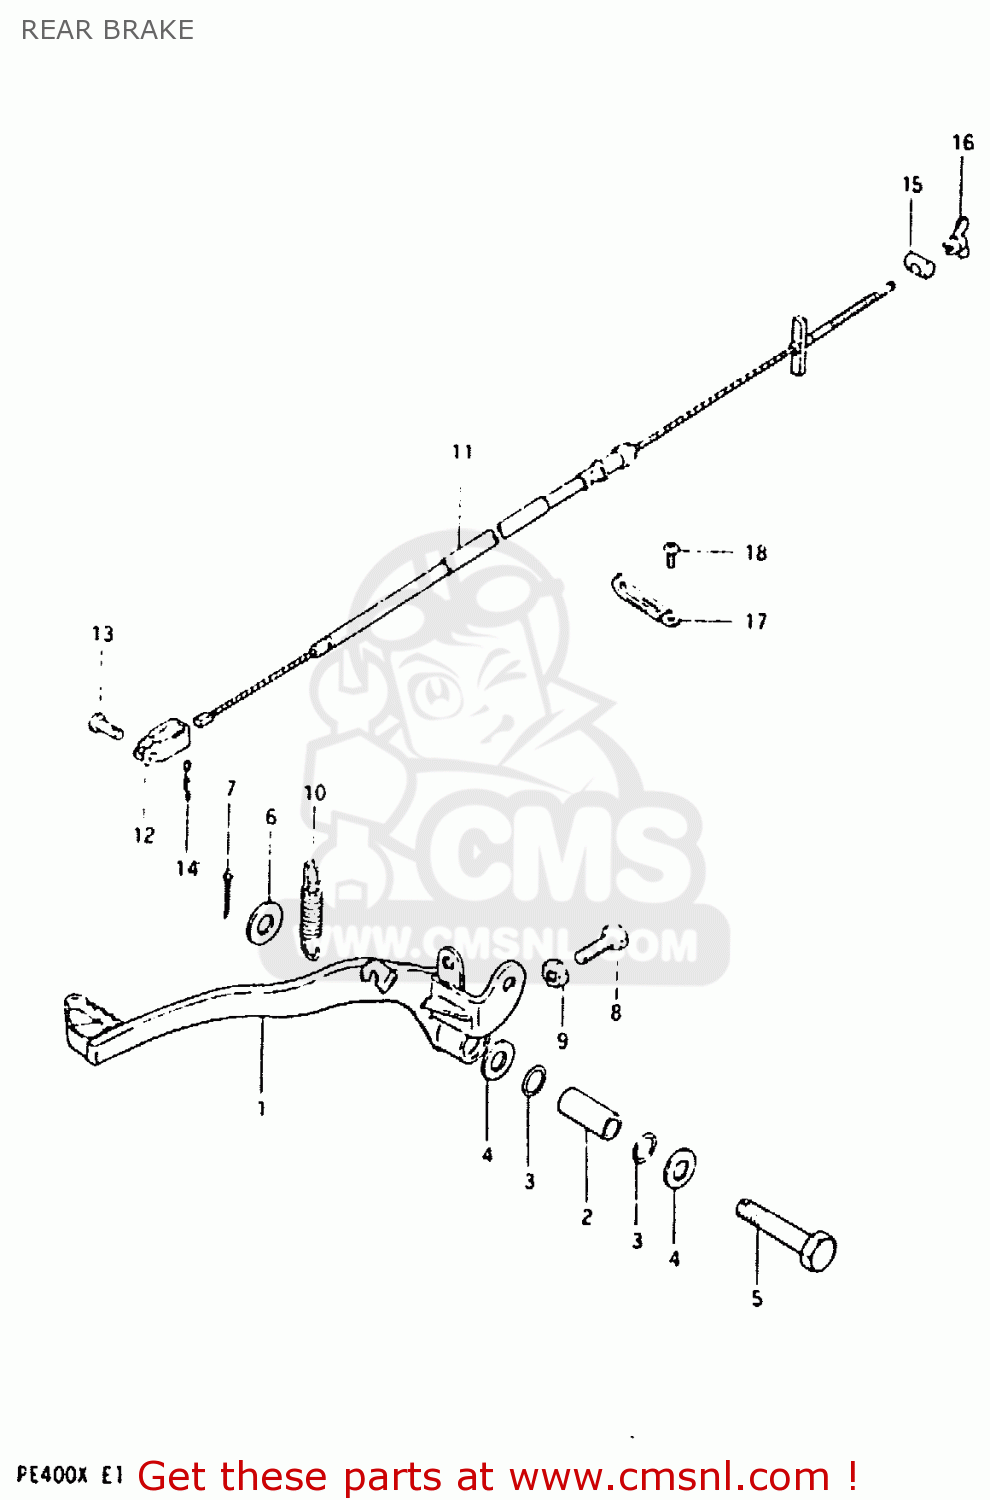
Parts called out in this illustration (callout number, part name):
1	PEDAL,BRAKE
2	SPACER (8X10X22)
3	O-RING (D:1.5 ID:10)
4	WASHER
5	BOLT 8X43.5
6	WASHER
7	PIN 20X20
8	BOLT 6X25
9	NUT
10	SPRING
11	CABLE,RR BRAKE
12	HOOK,REAR BRAKE PEDAL
13	PIN(L:13)
14	PIN
15	PIN
16	NUT
17	CLAMP
18	SCREW,6X6
